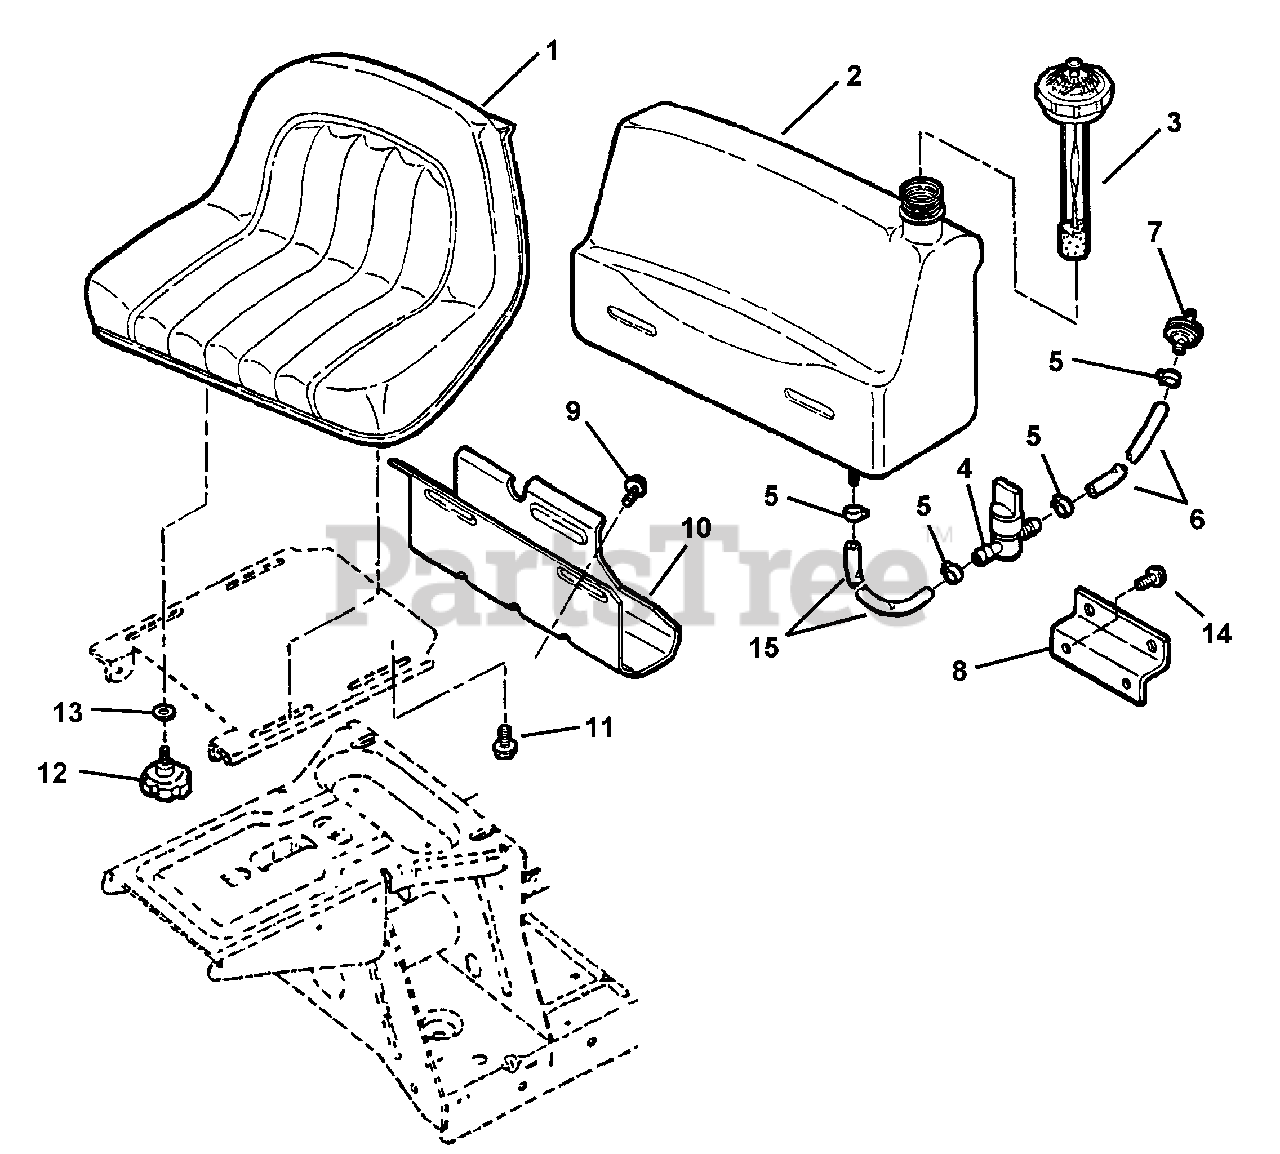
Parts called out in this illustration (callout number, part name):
1	SEAT, Operator (DeLuxe Back)
2	ASSEMBLY, Fuel Tank
3	CAP, Fuel Tank (With Gauge)
4	VALVE, Fuel Shut-Off
5	CLAMP, Fuel Line
6	HOSE, Fuel (5" Long)
7	FILTER, Fuel (In-Line)
8	BRACKET, Tank
9	SCREW, 5/16-18 x 5/8" Self-Tap
10	BRACKET, Fuel Tank (Rear)
11	BOLT, 5/16-18 x 1/2" Hex Fl Lock
12	KNOB, Seat Adjusting
13	SPACER, 5/16"
14	SCREW, 5/16-18 x 1/2" Hex Washer Head, Self-Tap
15	HOSE, Fuel (24-1/4" Long)
